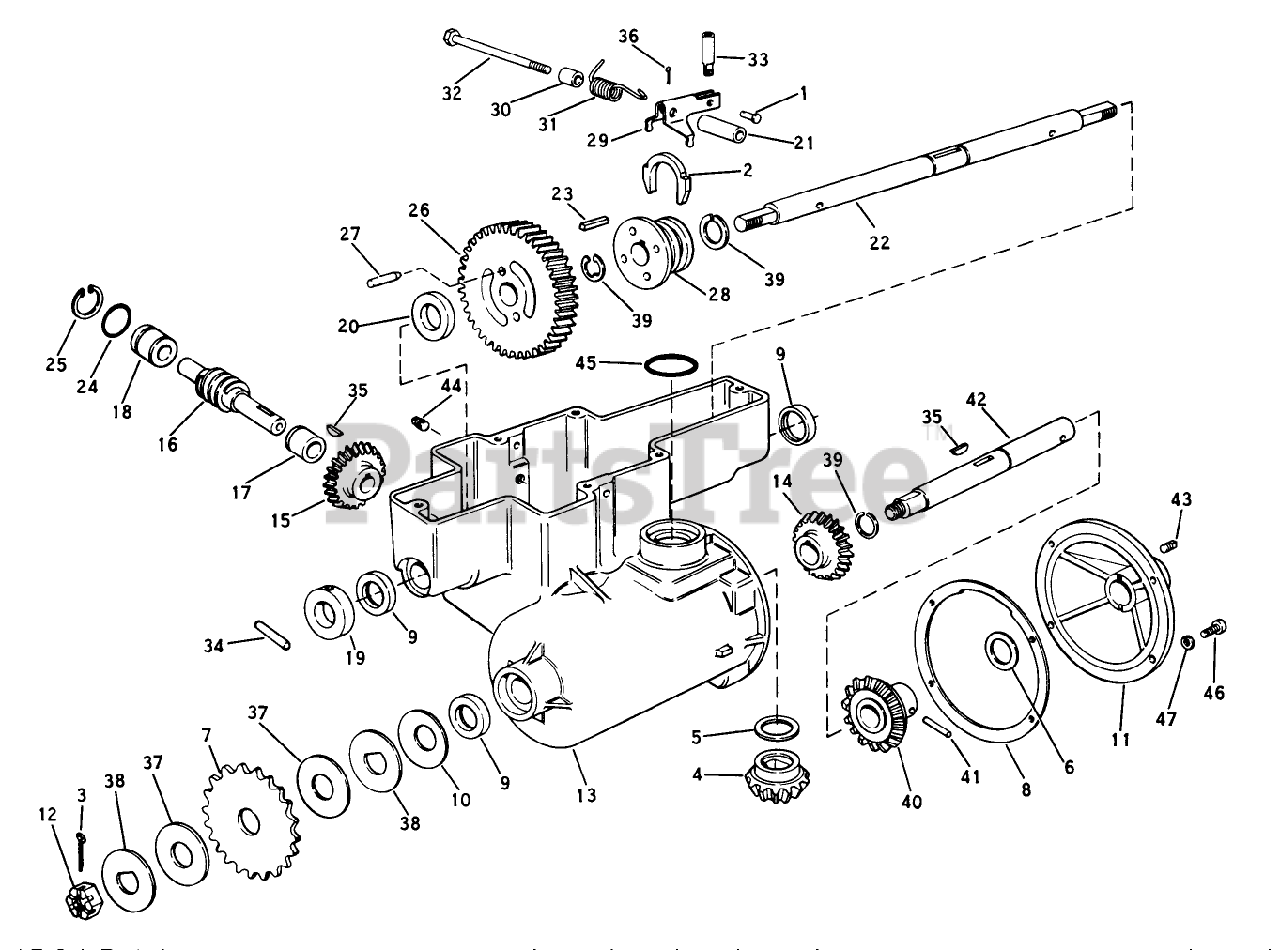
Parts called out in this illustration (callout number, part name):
3	Cotter Pin-Wheel
5	Thrust Washer-Pinion Gear
6	Thrust Washer-Driveshaft Gear
11	Cover-Gearcase
19	Collar-Axle
29	Lever-Drive Clutch
38	Washer-Steel
42	Driveshaft
43	Pipe Plug-Oil Fill-Gearcase
45	O Ring-G-case to Crankcase
46	Screw-Gearcase Cover
